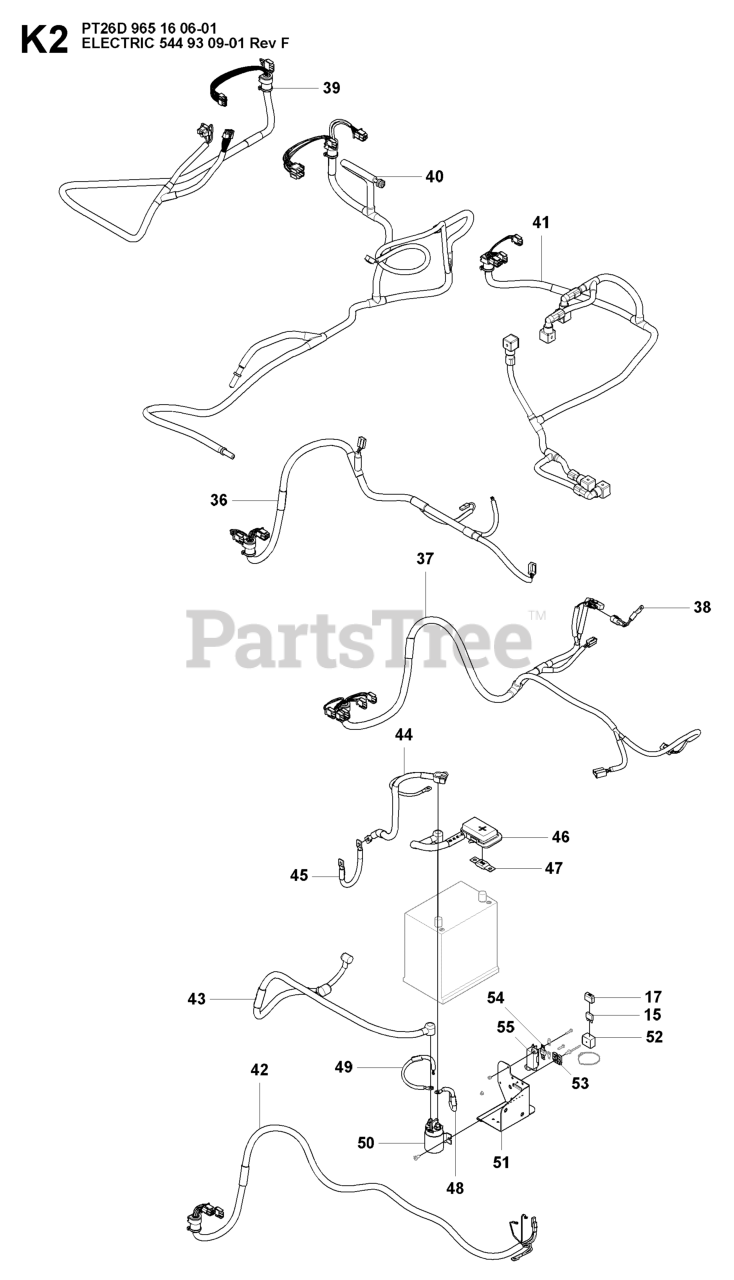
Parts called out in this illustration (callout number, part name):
17	COVER FUSE HOLDER
49	WIRING FUSE POWER
55	FUSE HOLDER
